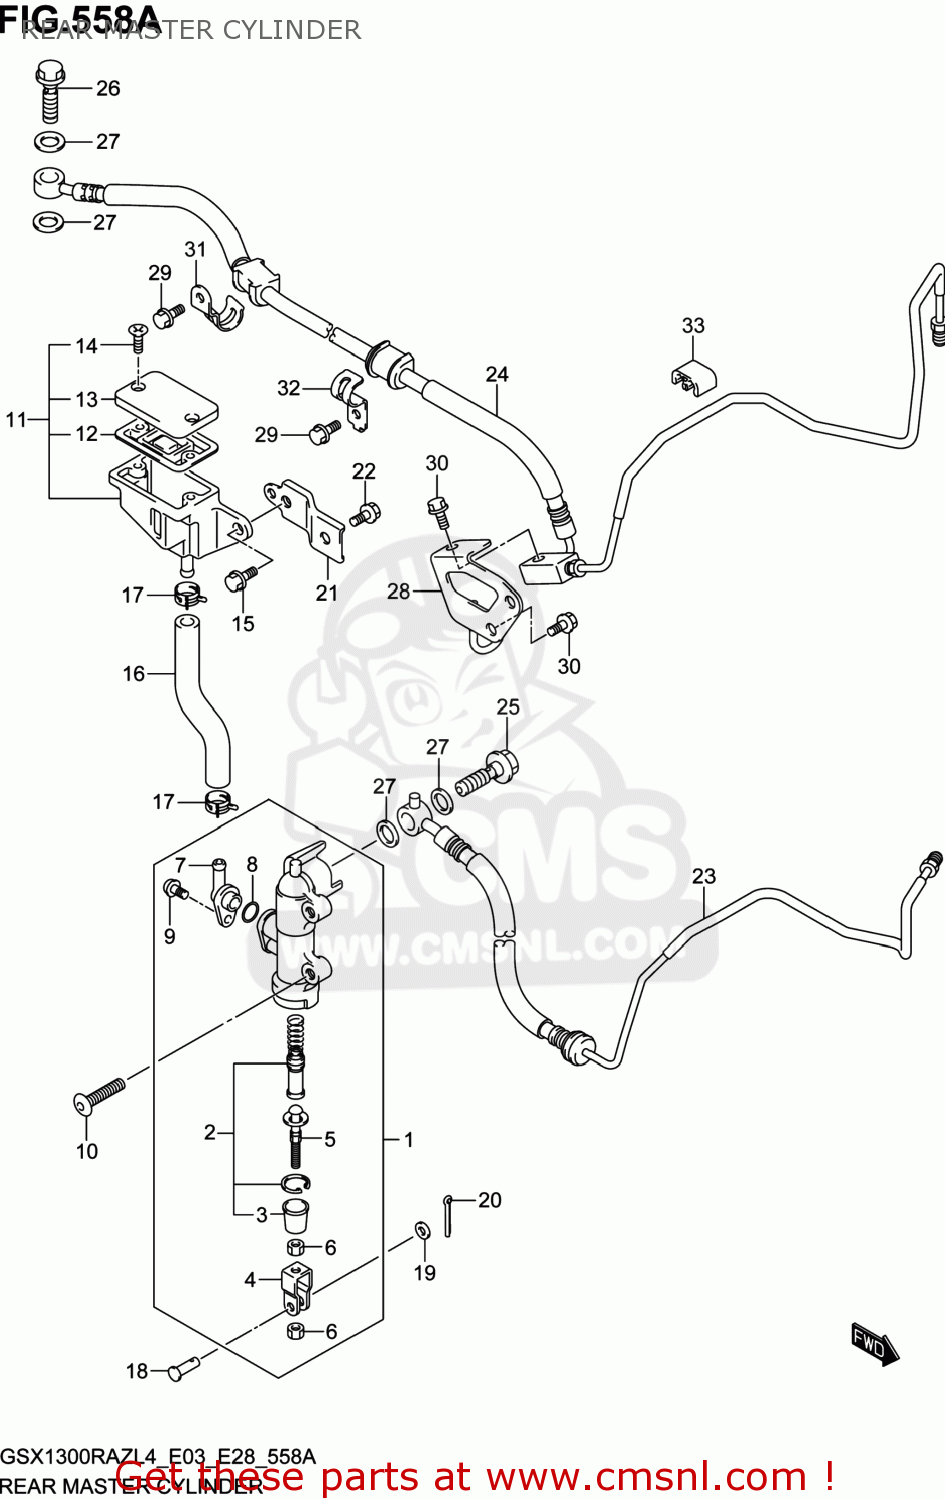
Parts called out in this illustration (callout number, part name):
1	CYLINDER ASSY,RR MASTER
2	PISTON/CUP SET
3	BOOT
4	YOKE
5	ROD,PUSH
6	NUT
7	CONNECTOR
8	O RING
9	SCREW
10	SCREW(6X20)
11	TANK ASSY,RR RESERVOIR
12	DIAPHRAGM
13	CAP
14	SCREW
15	BOLT
16	HOSE,RESERVOIR TANK
17	CLIP
18	PIN(6X18.2)
19	WASHER
20	PIN
21	BRACKET,RR RESERVOIR TANK
22	BOLT
23	HOSE ASSY,RR BRAKE NO.1
24	HOSE ASSY,RR BRAKE NO.2
25	BOLT UNION
26	BOLT UNION
27	WASHER(10X15X1.5)
28	CLAMP,RR BRAKE HOSE
29	BOLT
30	BOLT
31	CLAMP,RR BRAKE HOSE
32	CLAMP,RR BRAKE HOSE NO.1
33	CLAMP
